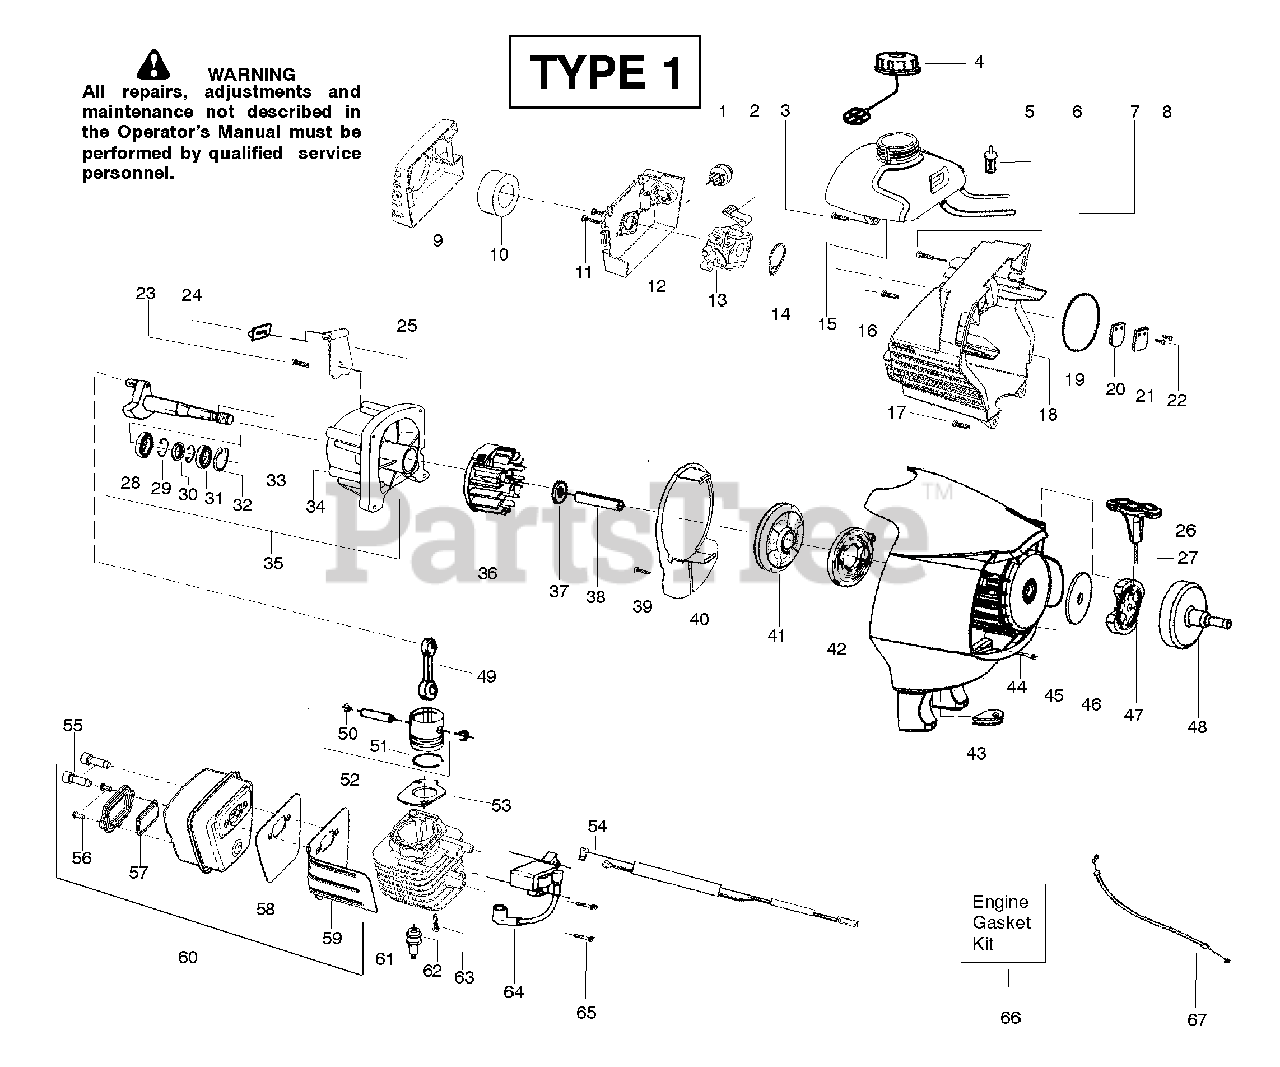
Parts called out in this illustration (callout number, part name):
1	Bulb-Purge
2	Kit-Choke Lever
3	Screw-tank
4	Cap-Fuel w/ret.
5	Assy-Fuel pickup
6	Kit-Fuel line
7	Kit-Fuel/Purge line
9	Cover-Air box
10	Filter-Air
11	Screw-Carb.
12	Box-Air
13	Kit-Carb assy.
14	Seal-Carb.
15	Assy-Fuel Tank
16	Screw-Crankcase
17	Screw-Shroud
18	Assy-Rear Shroud
19	O-ring-Shroud
20	Valve-Reed
21	Stop-Reed
22	Screw-Reed stop
23	Screw-Retainer
24	Isolator-Tank
25	Ret.-Tank
26	Handle-Starter
27	Kit-Rope
28	Bearing-Inner
29	Retainer
31	Bearing-Outer
32	Ret.-Crankshaft
33	Assy-Crankshaft
34	Assy-Crankcase
35	Assy-C'case/C'shaft
36	Assy-Flywheel
39	Screw-Baffle
40	Plate-Baffle
41	Kit-Pulley
42	Spring-Starter
44	Screw-F/hsg.
45	Assy-Fan Housing
46	Washer-Clutch
47	Assy-Clutch
48	Assy-Drum/Adapter
49	Assy-Conn. Rod
50	Ret.-Piston pin
51	Ring-Piston
52	Kit-Piston
53	Gasket-Cylinder
54	Assy-Leadwire
55	Bolt-Muffler 1/4"-20
57	Kit-Spark Arrestor
58	Gasket-Muffler
60	Kit-Muffler
61	Cylinder
62	Plug-Spark
63	Bolt-Cyl. 1/4"-20
64	Module-Ignition
65	Screw-Module
66	Kit-Gasket/Seal
67	Assy-Throttle cable
